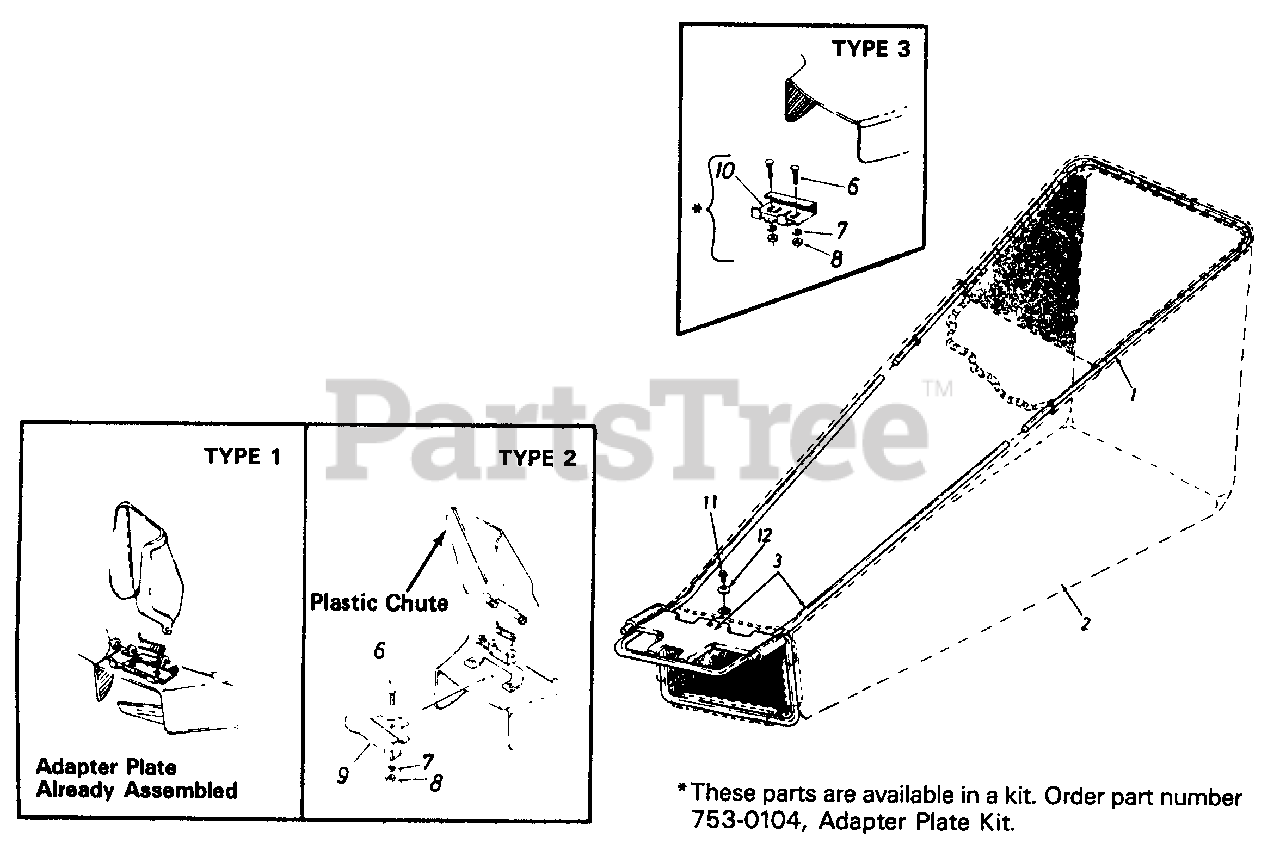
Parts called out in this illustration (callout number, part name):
1	Frame - Upper
2	Grass Catcher Bag
3	Frame Lower
6	Carriage Bolt
7	Lock Washer 1/4" I.D.*
8	Hex Nut 1/4-20 Thd.*
9	Adapter Plate
10	Adapter Plate
11	Self-Tap Scr. 1/4" x 1/2" Lg.
12	Bell-Wash. 1/4" I.D.
